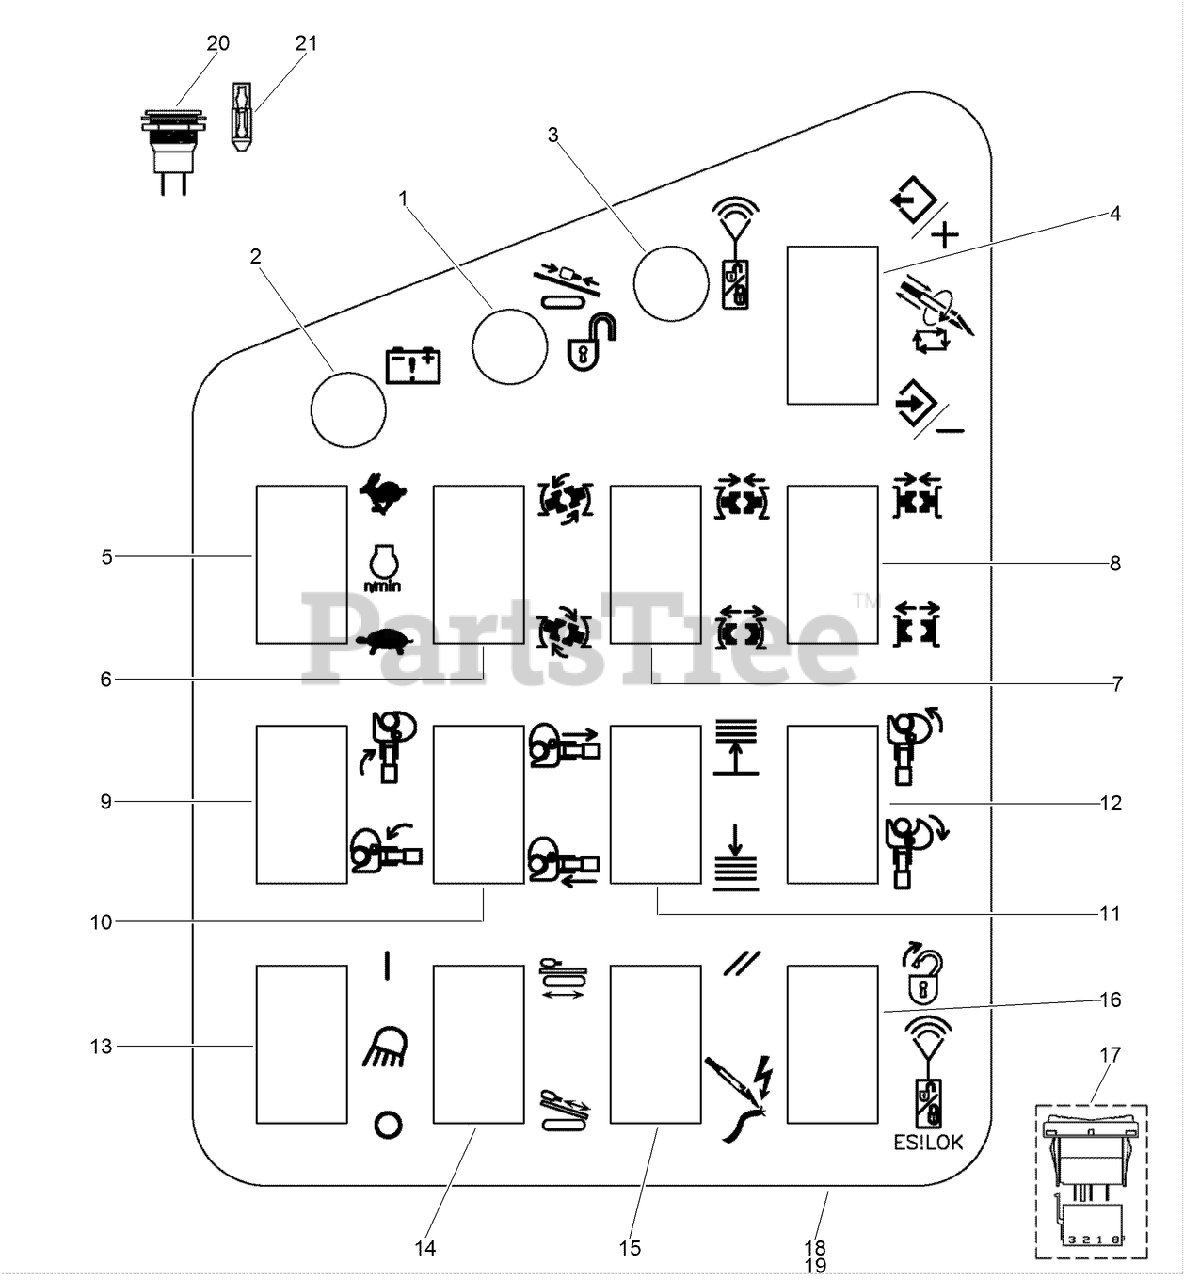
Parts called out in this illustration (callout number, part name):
1	LENS-DOME, FLUTED GREEN (TYPE T2)
2	LENS-DOME, FLUTED RED (TYPE T-2)
3	LENS-DOME, FLUTED AMBER (TYPE T2)
4	SWITCH - Rocker, (ON) - OFF - (ON)
5	SWITCH - Rocker, (ON) - OFF - (ON)
6	SWITCH - Rocker, (ON) - OFF - (ON)
7	SWITCH - Rocker, ON - OFF - (ON)
8	SWITCH - Rocker, ON - OFF - (ON)
9	SWITCH - Rocker, (ON) - OFF - (ON)
10	SWITCH - Rocker, (ON) - OFF - (ON)
11	SWITCH - Rocker, (ON) - OFF - (ON)
12	SWITCH - Rocker, (ON) - OFF - (ON)
13	SWITCH - Rocker, ON - OFF, 2 Pole
14	SWITCH - Rocker, ON - OFF, 2 Pole
15	SWITCH - Rocker, ON - (OFF)
16	SWITCH - Rocker, (ON) - OFF
17	CONNECTOR ASSEMBLY - Rocker Switch Kit
18	OVERLAY - 32GB9711L
19	PLATE - Cover, Left Console
20	TYPE T-2 SOCKET ASM
21	BULB-TYPE T-2, 12VOLT
